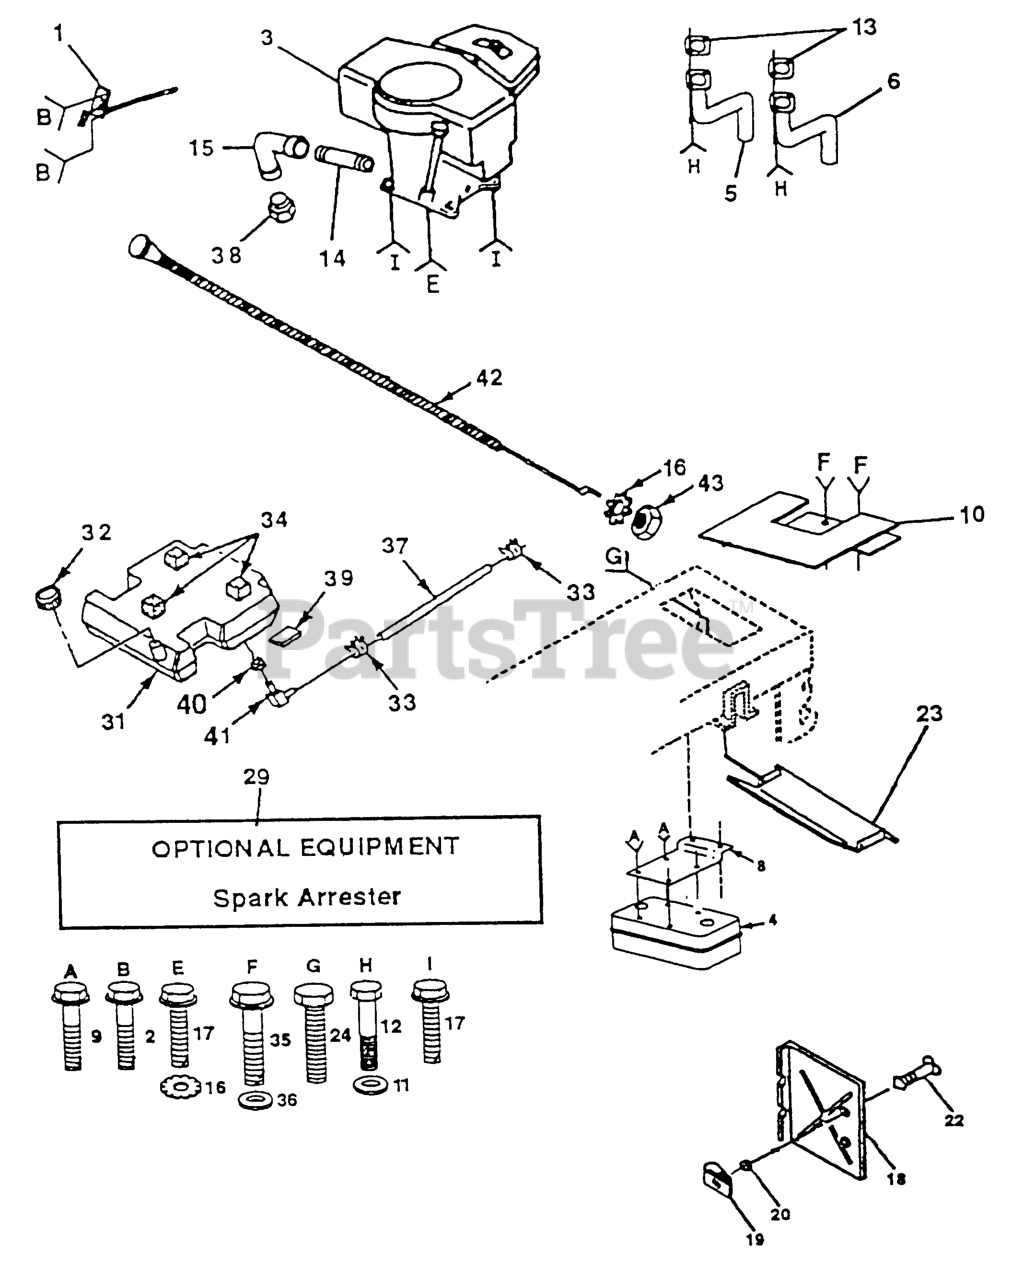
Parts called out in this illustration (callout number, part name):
1	THROTTLE CONTROL
2	SCREW LT
4	MUFFLER
5	MANIFOLD TUBE LH
6	MANIFOLD TUBE RH
8	BRACKET MUFFLER
9	SCREW ST
10	HEAT SHIELD
11	WASHER.LOCK.HVY.HLCL.SPR.5/16
12	Bolt. Fin Hex 1/4-20 x 3/4
13	Muffler Gasket
14	Nipple Pipe 3/8 Npt X 4-1/2"
15	ELBOW
16	LOCKWASHER
17	SCREW LT
18	HEAT SHIELD
19	RECEPTACLE LT
20	RETAINER LT
22	STUD 1/4 TURN
23	HEAT SHIELD
29	KIT.SPARK ARRESTOR 794945 B&S
31	FUEL TANK
32	FUEL CAP
33	HOSE CLAMP
34	PAD-SPACER LT
35	SCREW.THDROL.5/16-18X3/4.TTY
36	WASHER
37	FUEL LINE 54"
38	Plug Oil Drain
39	PAD IDLER TI
40	BUSHING OUTLET T
41	STEM FUEL TANK
42	CHOKE CONTROL
43	NUT
